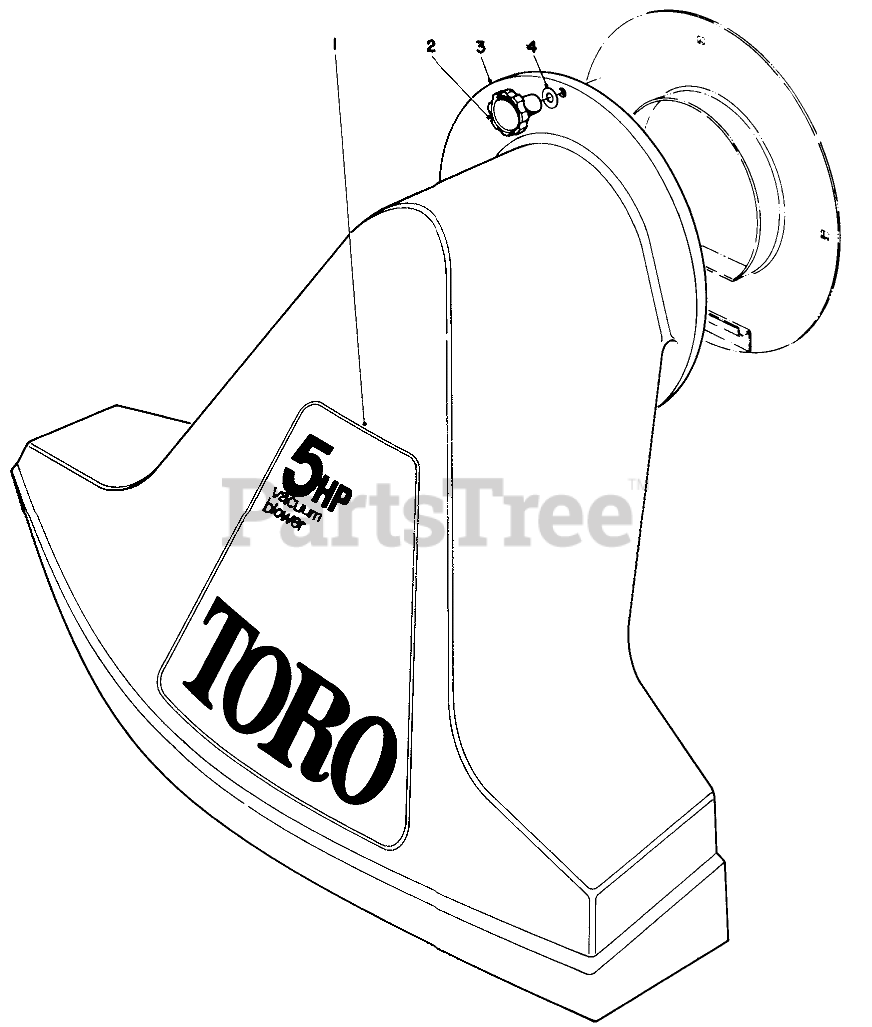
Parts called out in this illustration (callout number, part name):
1	Decal-Toro Model No. 62912
3	Snout
4	Washer
